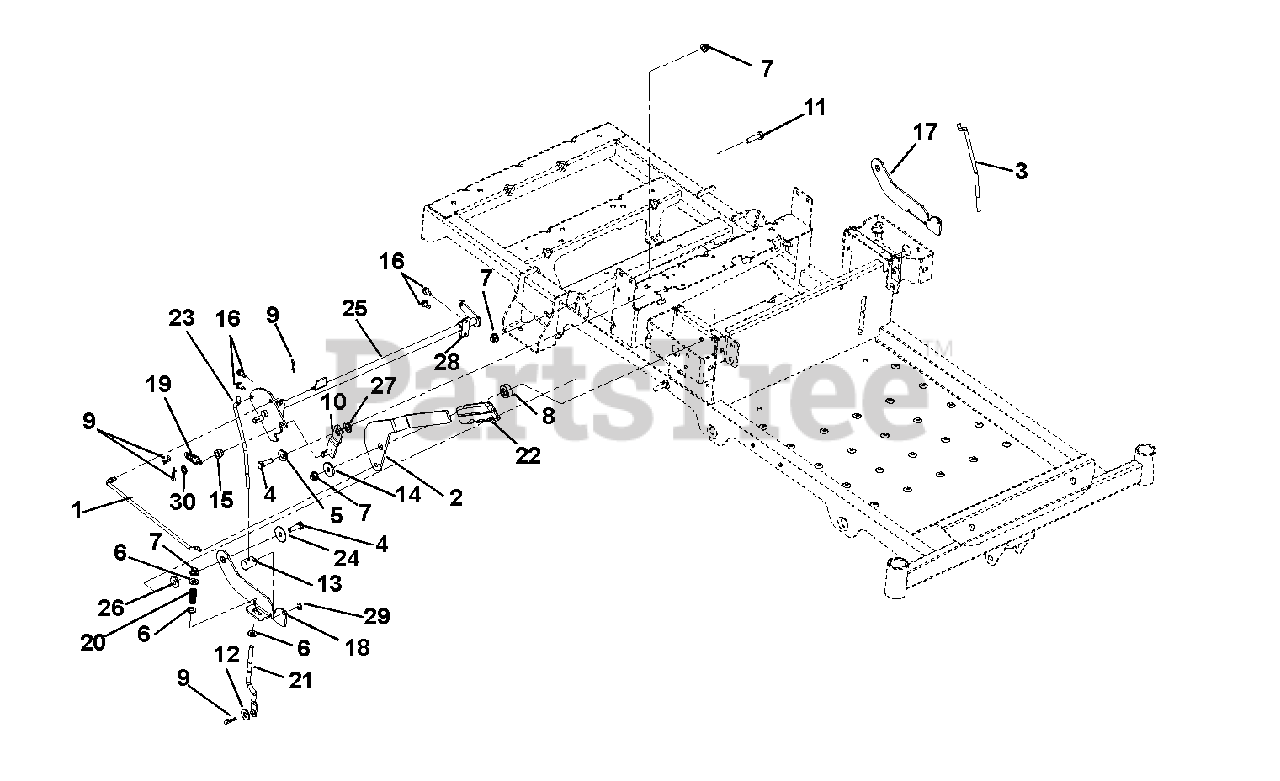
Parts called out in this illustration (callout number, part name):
1	Link, Brake Handle
2	Handle, Parking Brake
3	Link, Neutral Left Hand
4	Bolt, Hex .31-18 x 1.00
5	Bushing, Flange .312 x .500 x .344 x .880
6	Washer, Flat Steel .344 x .688 x .065
7	Nut, Flange Nyloc 5/16-18
8	Spacer, Brake Handle
9	Pin, Hair Internal .08 x .18 x 1.18
10	Weldment, Detent Arm
11	Bolt, Hex .31-18 x 1.25
12	Washer, Flat Steel .38 x .875 x .083
13	Trunnion, 1/4-20
14	Washer, Flat Steel .344 x 1.125 x .135
16	Screw, Tapping .25-20 x .50 Hex Washer Head
17	Latch, Left Hand Neutral
18	Latch, Right Hand Neutral
19	Spring, Tension .072 x .565 x 1.87
20	Spring, Compression
21	Link, Brake Cog
22	Grip, Parking Brake
23	Link, Neutral Right Hand
24	Washer, Flat Steel .347 x 1.254 x .048
25	Weldment, Brake Shaft
26	Bushing, Flange .325 x .499 x .26 x .88
27	Washer, Flat Steel .52 x .827 x .062
28	Bushing, .50 Clamp Block Molded
29	Ring, Retaining, External .250 x .025
30	Washer, Steel .385 x .745 x .030
